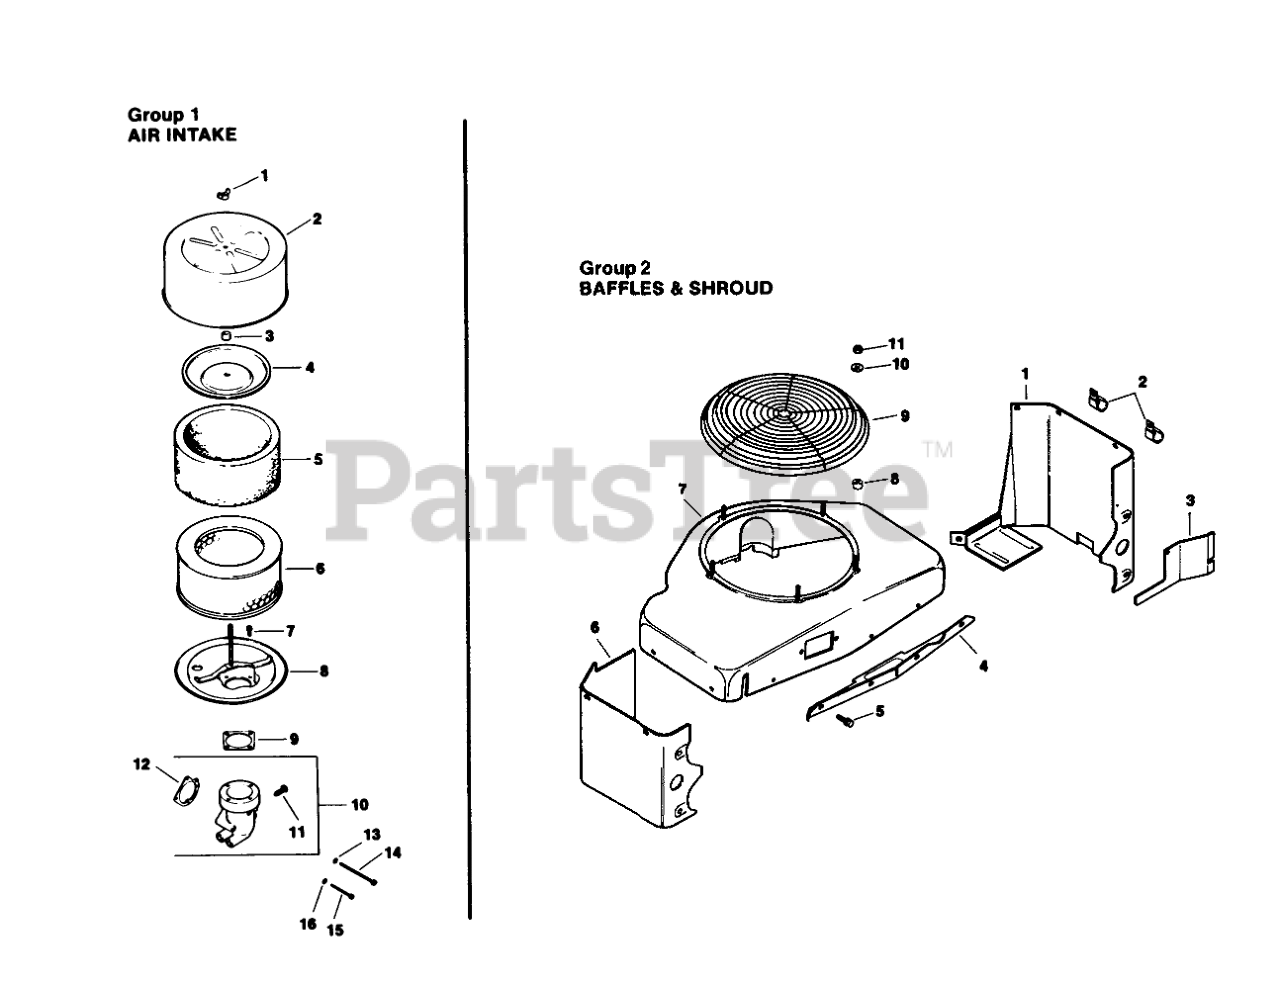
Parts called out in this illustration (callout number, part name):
1	Nut-Wing
1	Baffle-Cylinder Head
2	Cover-Air Cleaner
3	Seal
3	Baffle-Cylinder Head
4	Cover-Air Clean Element
4	Support-Upper Housing
5	Precleaner
5	Screw
6	Element
6	Baffle-Cylinder Head
7	Screw-H.C.
7	Housing-Blower
8	Base-Air Cleaner
9	Gasket-Air Cleaner
9	Guard-Grass Screen
10	Kit-Elbow (Incl. Ref. #11 & 12)
11	Screw-Hex Hd
12	Gasket-Elbow
13	Washer
14	Screw-R.H.M.
15	Screw-R.H.M.
16	Washer
20	Seal-Rear Oil
28	Screw-Hex Washer Hd.
